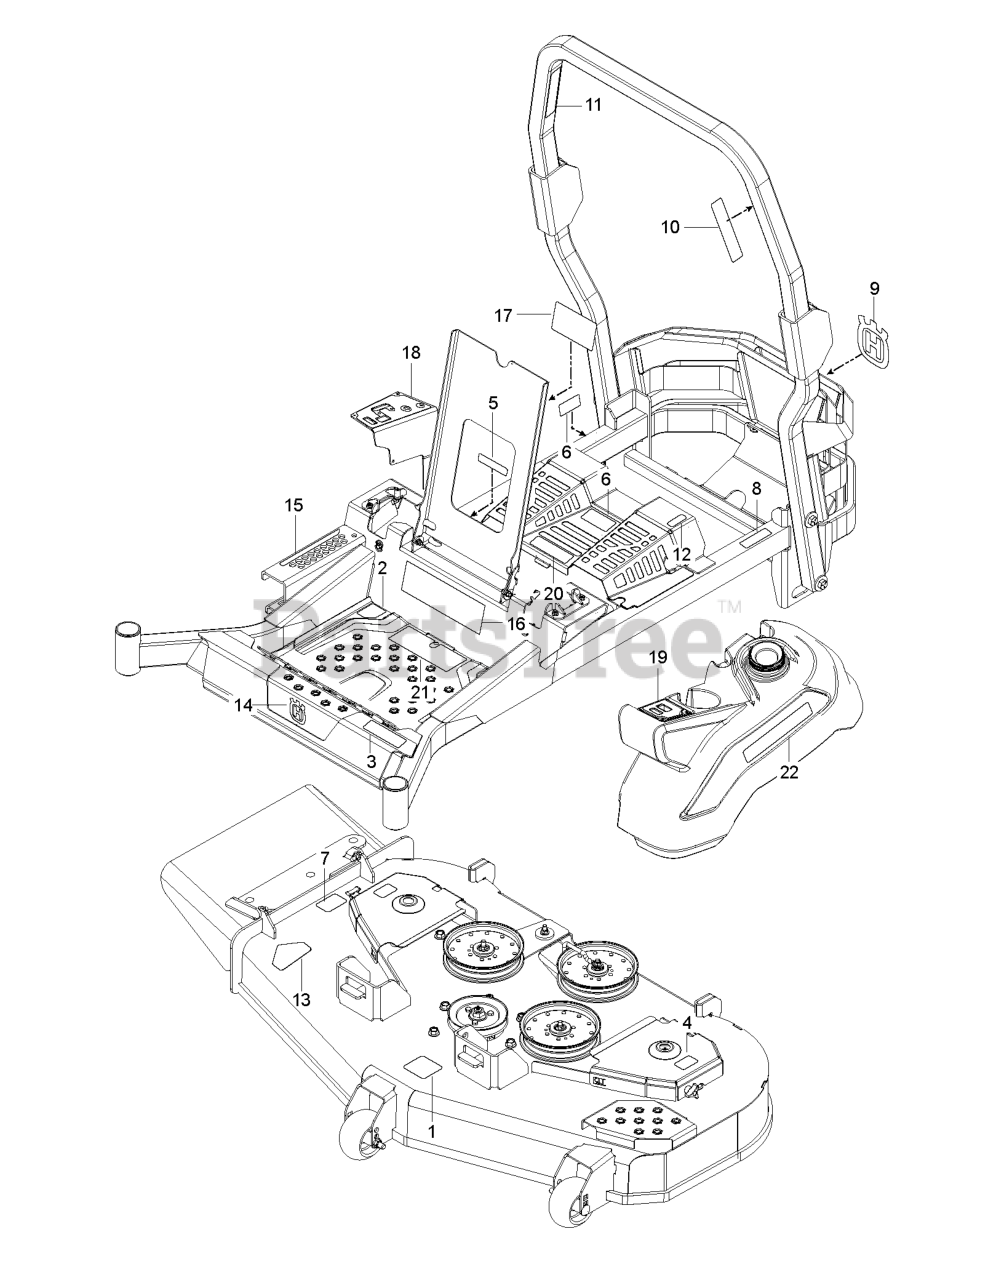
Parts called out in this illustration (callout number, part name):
1	DECAL, BELT ROUTING
2	DECAL.ZTR.SADLE.WARN.PZ500.ENG
3	DECAL.ZTR.PZ500SERIES.MODEL.Z5
4	DECAL.DECK.6MIL.EURO.NOSTEP
5	EURO DECAL-BATTERY WARNIN6
6	DECAL, BELT DRIVE
7	DECAL.DECK.6MIL./DEF.SHLD.WARN
8	DECAL, WARNING SPARK ARRESTOR
9	DECAL, CROWN H, 110MM
10	DECAL, ROPS
11	DECAL, ROPS, WARNING
12	DECAL, FUSE
13	DECAL, DECK DEFLECTOR, WARNING
14	DECAL.AUGER.HUSQ.CROWN.SNOW
15	DECAL.PZ500.DECKLIFT.HUSQ
16	DECAL.ZTR.SADDLE.COMM.PZ500
17	DECAL.PZ500.MAINTANCE/SVC.2018
18	DECALZTR.CONTROLPANEL.PZ500.RH
19	DECAL.ZTR.CONTROLPANL.PZ500.LH
20	DECAL.ZTR.TRANCOVER.WARN.PZ500
21	DECAL.ZTR.SADLE.WARN.PZ500.ENG
22	DECAL.HUSQVARNA.210MM
